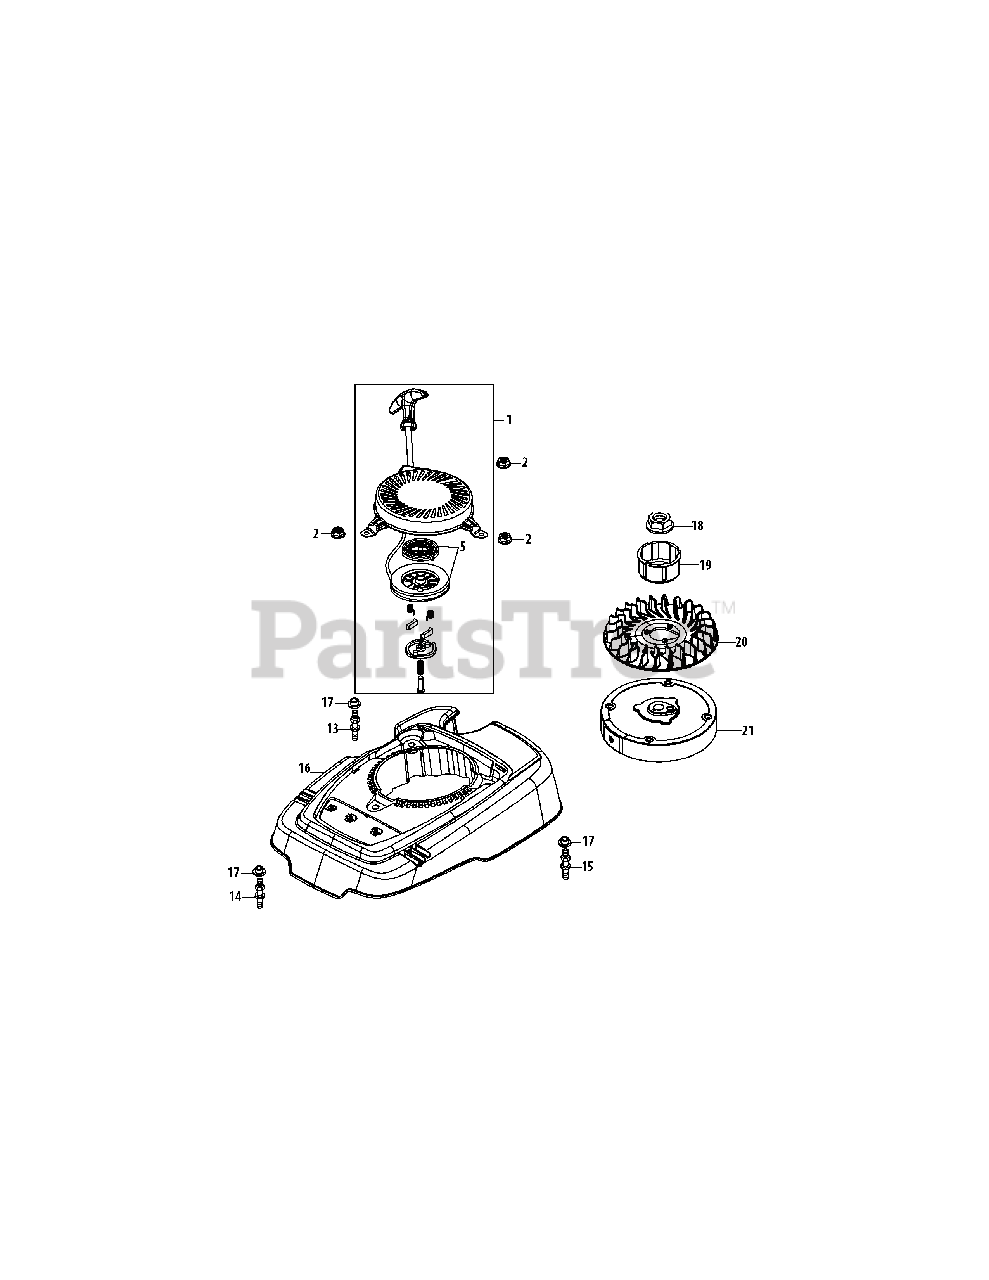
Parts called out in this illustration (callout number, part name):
1	Recoil Starter Assembly
2	Nut M6
5	Recoil Spring
13	Shroud Stud M6×85-48
14	Shroud Stud M6×87-51.5
15	Shroud Stud M6×79
16	M6 Inner Shroud
17	Spacer
18	Nut M14×1.5
19	Starter Cup
20	Cooling Fan
21	Flywheel
